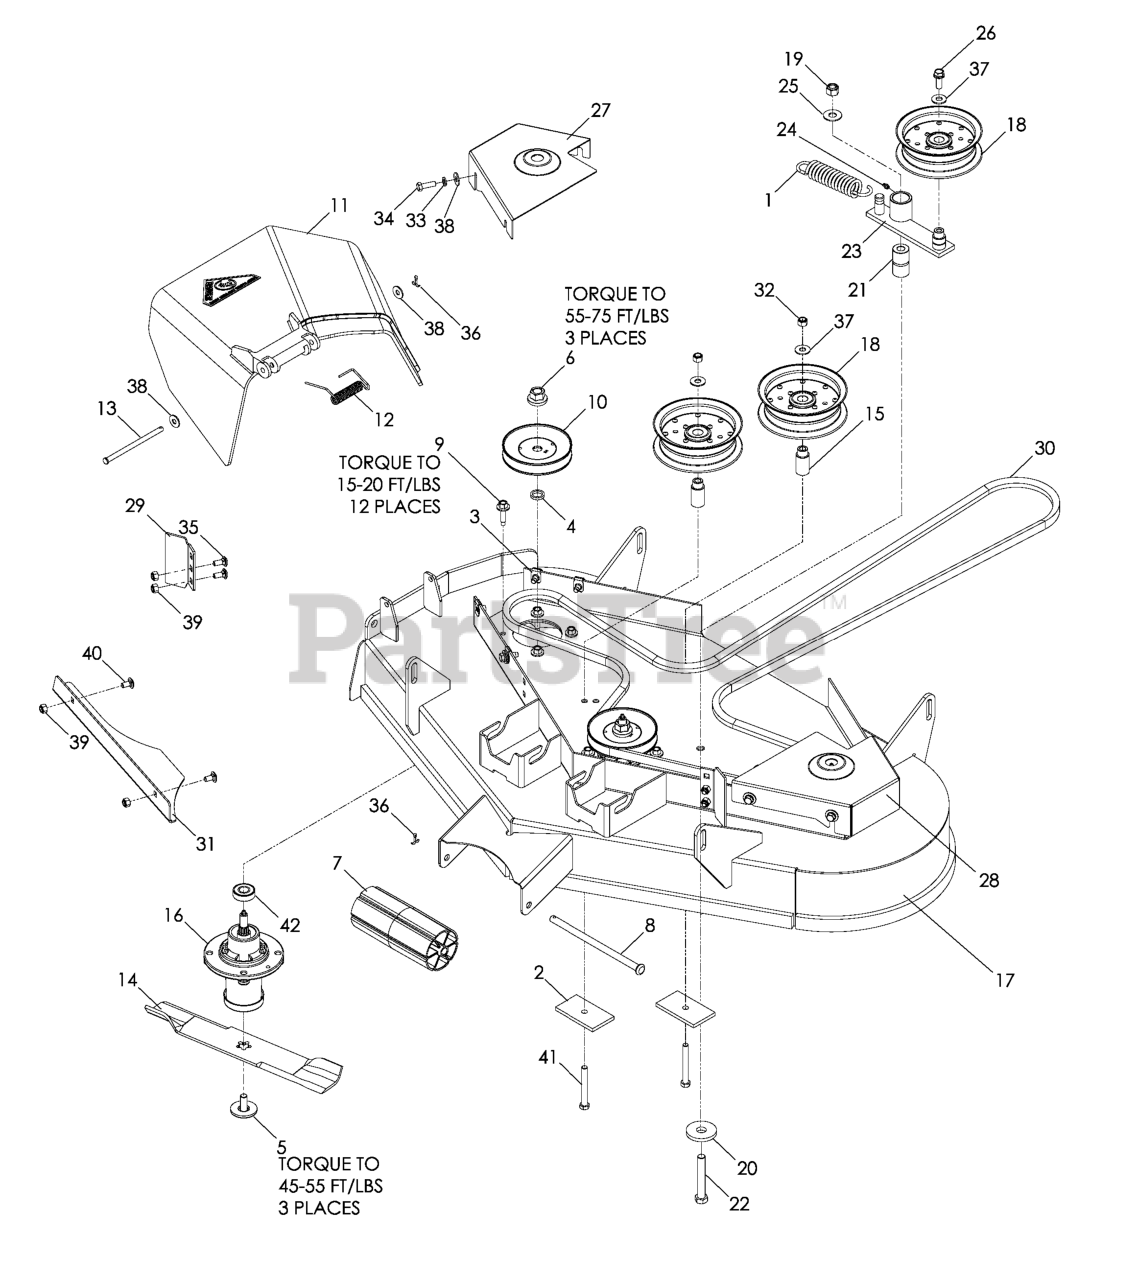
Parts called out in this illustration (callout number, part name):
2	SUPPORT PLATE
3	U-CLIP 5/16-18 NUT RETAINER
4	WASHER-SPACER
5	BLADE BOLT ASSY-7/16" TB REPL
6	LOCKNUT - 9/16
7	NOSE ROLLER 48"
8	NOSE ROLLER ROD
9	WASHER HEAD SCREW
10	PULLEY MANDREL
11	DISCHARGE CHUTE 42"
12	SPRING - TORSION
13	PIN-CLEVIS 5/16 DIA X 5.19 ZD
14	BLADE, 14 5/8"
15	IDLER BUSHING
16	MANDREL.DECK.ASSEMBLY
17	DECK W/DECALS 42"
18	PULLEY, IDLER
19	NUT 1/2-13 HEX NYLOC ZD
20	WASHER, SUPPORT
21	PIVOT BUSHING
22	HCS 1/2C X 3 1/4
24	ZERK
25	WASHER 1/2 FLAT
26	4CS 3/8C X 1 SERRATED HEAD
27	BELT SHIELD, RIGHT 42, ORG
28	BELT SHIELD, LEFT 42, ORG
30	BELT, DECK 42"
31	CONFINEMENT.PLATE.42".BLACK
32	NUT 3/8-16 NYLOC
33	WASHER.LOCK.HVY.HLCL.SPR.5/16
34	HCS 5/16C X 1
35	BOLT 5/16C X 3/4" CARRIAGE
36	RP_COTTER PIN 1/8 X 3/4
37	WASHER 3/8 FLAT
38	WASHER 5/16 FLAT
39	NUT 5/16 NYLOC
40	CARRIAGE BOLT 5/16C X 5/8"
41	HCS 3/8C X 3
42	BEARING, BALL
